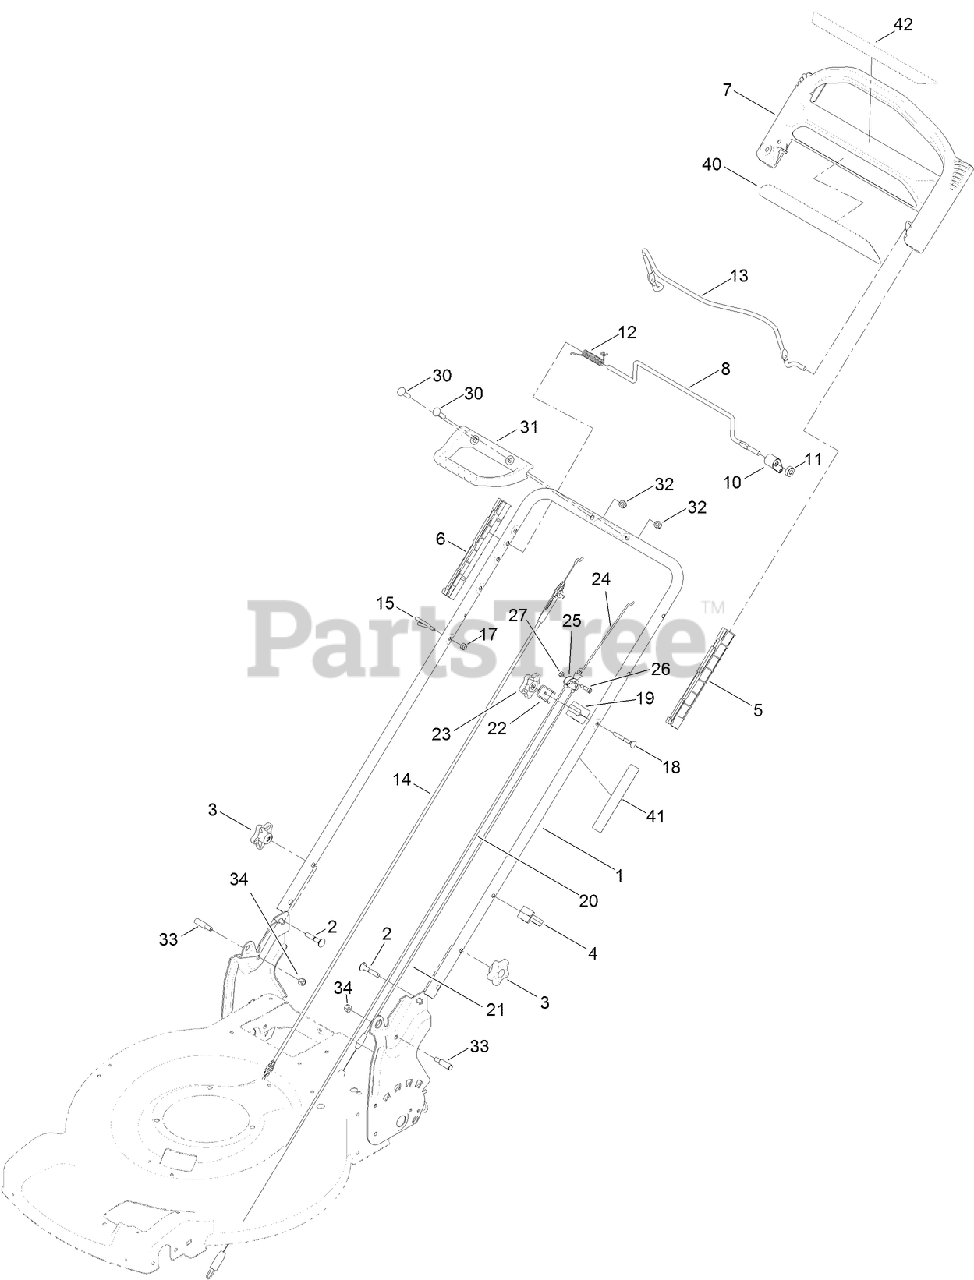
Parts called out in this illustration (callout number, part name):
2	SCREW-CARR
3	KNOB-HANDLE
4	GUIDE-CABLE
5	GUIDE-LH
6	GUIDE-RH
7	HANDLE-CONTROL
10	LEVER-TRACTION
11	SPACER
13	BAIL-BRAKE
14	CABLE-BRAKE
15	GUIDE-ROPE
17	NUT-LOCK, NI
18	SCREW-HANDLE
19	MOUNT-CABLE, TRACTION
20	CABLE-TRACTION, FRONT
21	CABLE-TRACTION, REAR
23	KNOB-HANDLE, LOCKING
24	LINKAGE-EQUALIZER
25	YOKE-CABLE
26	SCREW-SHOULDER
27	NUT-LOCK, NI
30	BOLT-CARRIAGE
31	HANDLE-ASSIST, TRACTION
32	NUT-ACORN
33	BOLT-SHOULDER
34	NUT-LOCK, NI
41	DECAL-TRACTION, ADJUST
42	DECAL-ASSIST, TRACTION
